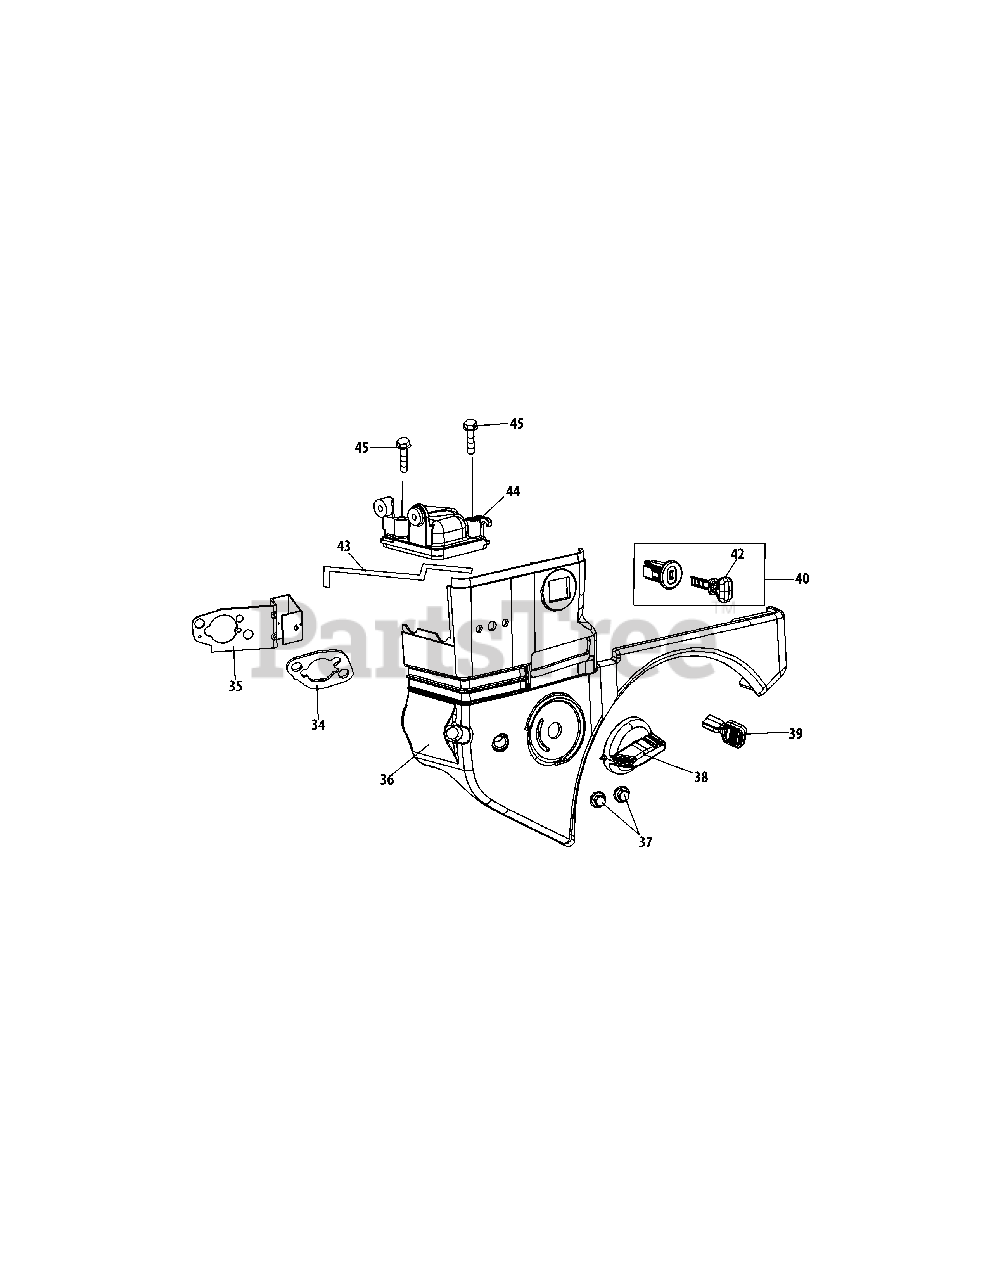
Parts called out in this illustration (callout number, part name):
34	Carburetor Gasket Plate
35	Choke Control
36	Engine Shroud
38	Choke Knob
39	Throttle Control Knob
40	Ignition Switch Assembly
42	Key
43	Choke Push Rod
44	Heater Box
45	Bolt M6×25
